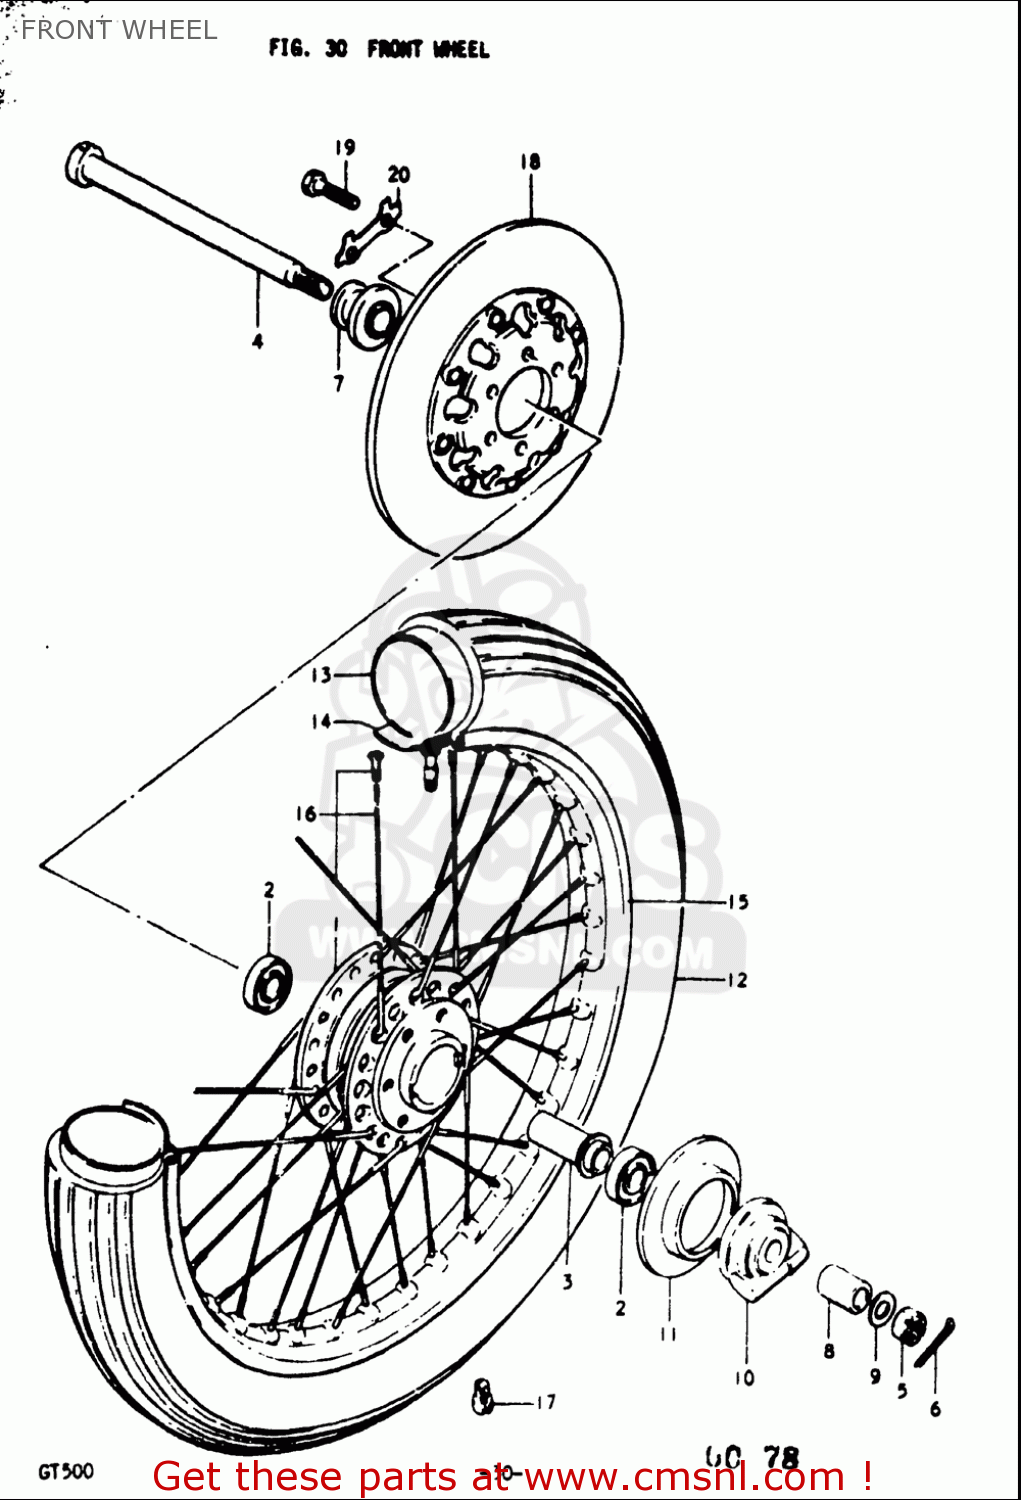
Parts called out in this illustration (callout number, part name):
1	HUB,FRONT WHEEL
3	SPACER,FR HUB BEARING
4	AXLE,FRONT
5	NUT 12MM
6	PIN
7	SPACER,FR AXLE,R
8	SPACER(15X22X30)
9	WASHER
10	BOX ASSY,SPEEDOMETER GEAR
13	TUBE ASSEMBLY,WHEEL,INNER
14	PROTECTOR,WHL INR TUBE
15	RIM,FR WHEEL
16	SPOKE ASSY,FR
17	BALANCER,WHEEL (B)
19	BOLT(8X30)
20	WASHER
